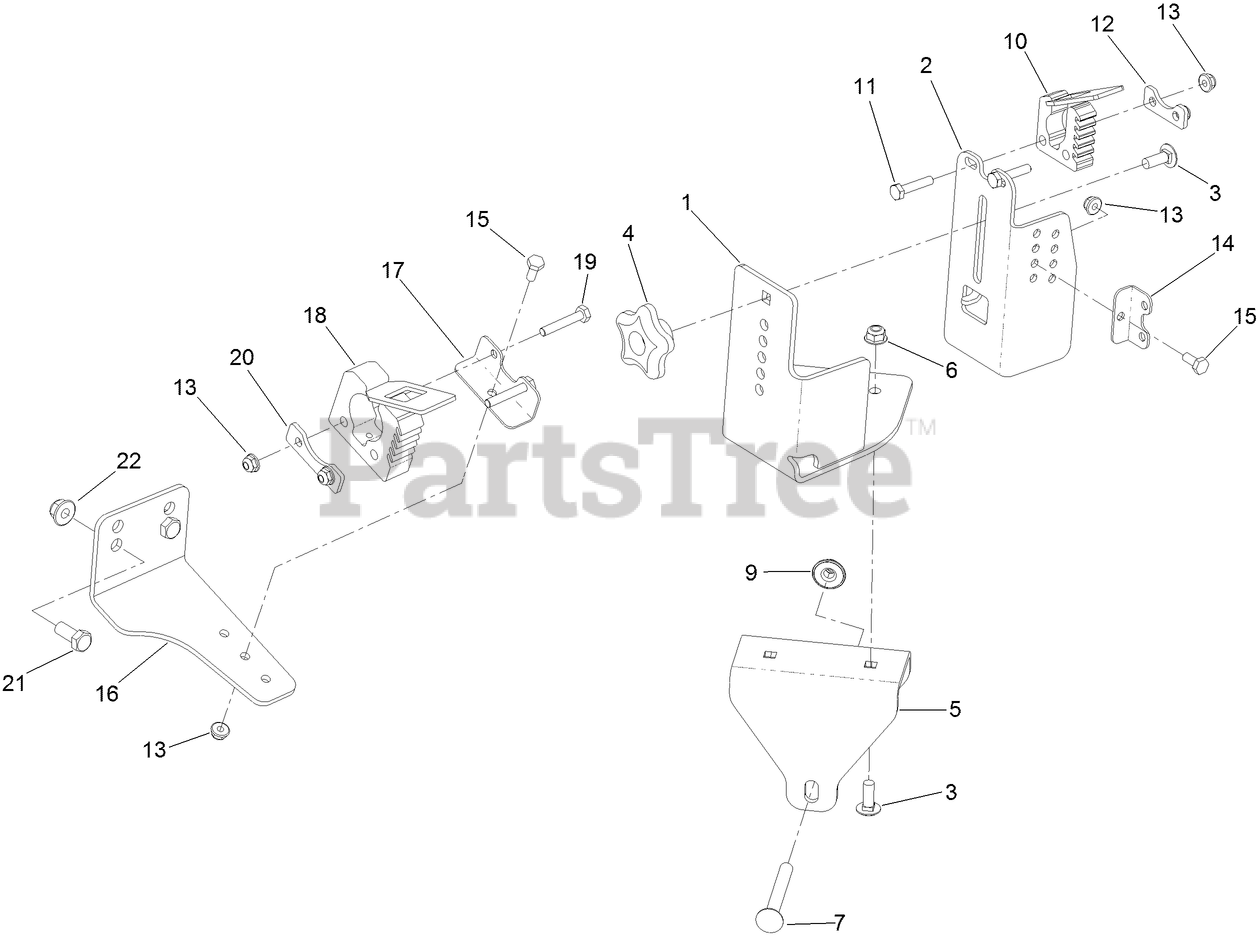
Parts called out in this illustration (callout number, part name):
1	PLATE-MOUNT, TRIMMER
2	PLATE-TRIMMER, ADJ.
3	BOLT-CARR
4	KNOB-HANDLE
5	CHANNEL-BRACKET, WEIGHT
6	NUT-HF, NI
7	SCREW-CARR
9	NUT-FLANGE, NI
10	CLAMP-QUICK FIST, MINI
11	SCREW-HH
12	PLATE-BACKER, SMALL
13	NUT-HF
14	BRACKET-QUICK FIST, SMALL
15	SCREW-HH
16	BRACKET-TRIMMER, REAR
17	BRACKET-QUICKFIST, LARGE
18	CLAMP-QUICK FIST, ORIGINAL
19	SCREW-HH
20	PLATE-BACKER, LARGE
21	SCREW-HH
22	NUT-HF, NI
